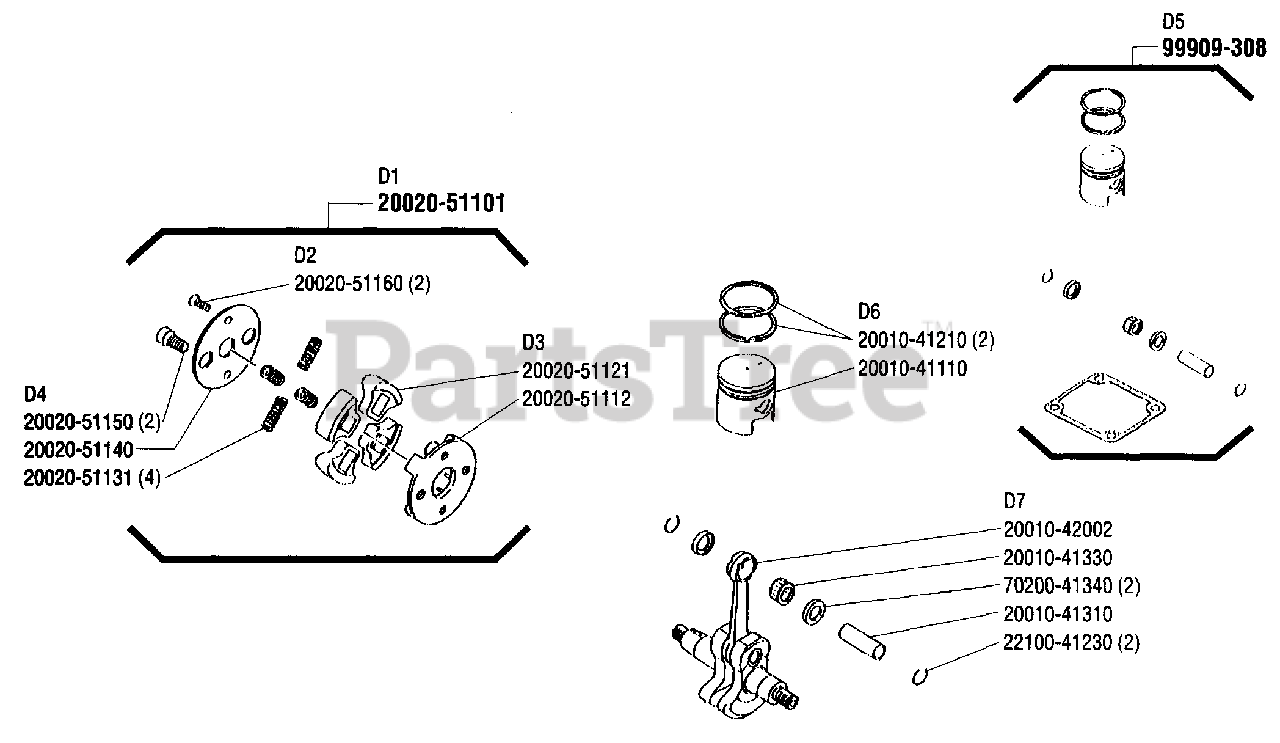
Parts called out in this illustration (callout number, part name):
D1	CLUTCH SHOE ASSY
D2	SCREW
D3	HUB, CLUTCH
D3	SHOE, CLUTCH
D4	SPRING, CLUTCH
D4	PLATE, CLUTCH
D4	BOLT, CLUTCH
D5	PISTON ASSY
D6	PISTON
D6	RING, PISTON
D7	PIN, PISTON
D7	BEARING, NEEDLE
D7	CRANKSHAFT ASSY
D7	RING, RETAINING
D7	WASHER, THRUST
